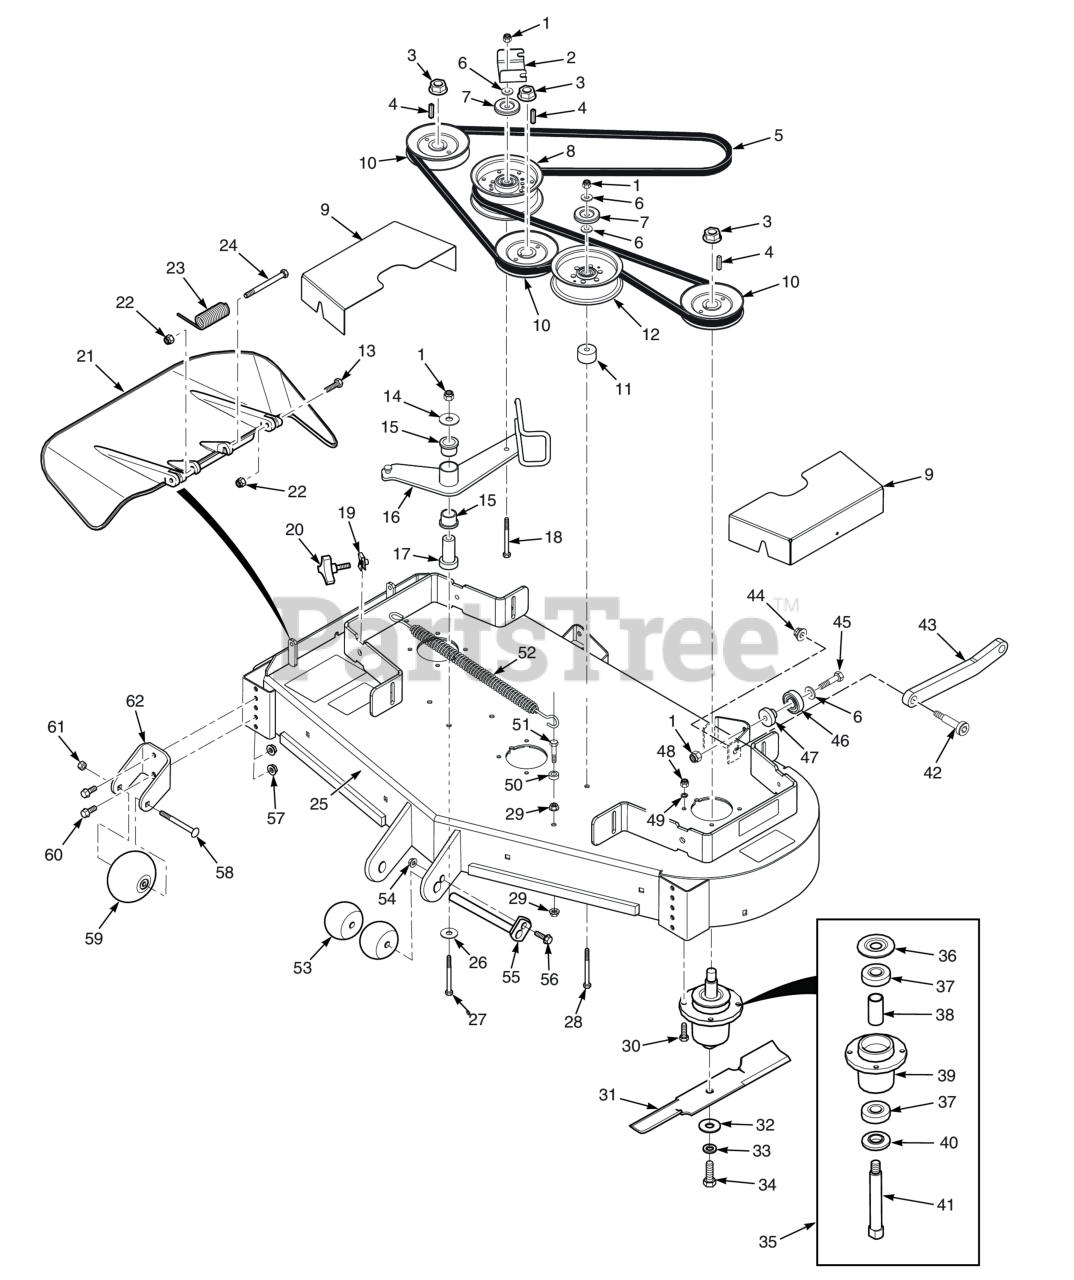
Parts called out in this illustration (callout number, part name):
1	HEX NUT, ELASTIC STOP LOCK, 3/8-16
2	Bracket, Belt Guide
3	Nut, 3/4-16 Spriral Lock
4	Key, 1/4 x 1/4 x 1.25" Pulley Mtg.
5	Belt, Cutter Deck
6	Flatwasher, 3/8 (.391 x .938 x .105 HD) Grade 8
7	Quick Pin, 5/16" Dia.
8	Pulley, Idler 5" Dia.
9	Belt Cover
10	Pulley, 5.73" OD - 25mm Bore
11	Spacer, Idler Pulley
12	Pulley, 5" Idler
13	Bolt, Hex Head 5/16-18 x 1-1/2" - Front
14	Flatwasher, 3/8-.406 x 1-1-1/2 x 7 Gauge
15	Bearing, Plastic
16	Idler Arm (incl. item #15)
17	Pivot, Idler
18	Capscrew, Hex Head 3/8-16 x 3.25"
19	U-Nut, 3/8-16
20	Knob, w/stud 3/8-16 x 1-1/4"
21	Discharge Chute Assy. SFZ52
22	HEX NUT, ELASTIC STOP LOCK, 5/16-18
23	Spring, Discharge Chute
24	Bolt, 5/16-18 x 4-3/4" Hex Head
25	Cutter Deck w/Decals, SMWZT-52
26	Flatwasher, 3/8-.406 x 2.25" x .1875
27	Capscrew, Hex Head 3/8-16 x 3-3/4"
28	Bolt, Hex Head, 3/8-16 x 3-1/2"
29	NUT, 3/8-16 SERRATED FLANGE HEX HEAD
30	Bolt, Hex Head 5/16-18 x 1-1/2" Grade 8
31	Cutter Blade, 18" (52V)
32	Flatwasher, 5/8-.688 x 1-3/4 x .134 HD
33	Lockwasher, 5/8" Spring
34	Bolt, Hex Head 5/8-11 x 1-1/2"
35	Spindle Assembly
36	Debris Shield
37	Bearing
38	Spacer, Bearing
39	Spindle Housing Assembly
40	Protector, Bearing
41	Shaft, Spindle
42	Bolt, Shoulder 1/2 x 3/8-16 x 2-3/4"
43	Pusharm
44	Nut, Flange Elastic Stop Nut, 3/8-16
45	Bolt, Hex Head 3/8-16 x 1-3/4" (Kohler EFI)
46	Bearing
47	Spacer, Bearing
48	Lock Nut, 5/16-18 Elastic Stop Grade 8
49	Lockwasher, 5/16 (.317 x .586 x .078) Helical Spring
50	SPACER, IDLER
51	Bolt, Hex Head 3/8-16 x 1-1/2" Grade 8 Black
52	Spring, L.H. Deck Drive
53	Wheel, Anti-Scalp
54	Nut, Serrated Flange 5/16-18 (Right Front Engine Mounting, Briggs and Kohler Only)
55	Shaft Weldment, Guide Roller
56	Bolt, Heax Head 5/16-18 x 1" (48V / 52V)
57	NUT, 3/8-16 SERRATED FLANGE HEX HEAD
58	Bolt, Hex Head 3/8-16 x 3-1/2"
59	Bolt, Carriage 3/8-16 x 4"
60	Capscrew, 3/8-16 x 1.0" Serrated Flange Hex Hd
61	Bolt, Hex Head 3/8-16 x 1" Ser. Flg.
62	Bracket, Anti-Scalp Wheel
